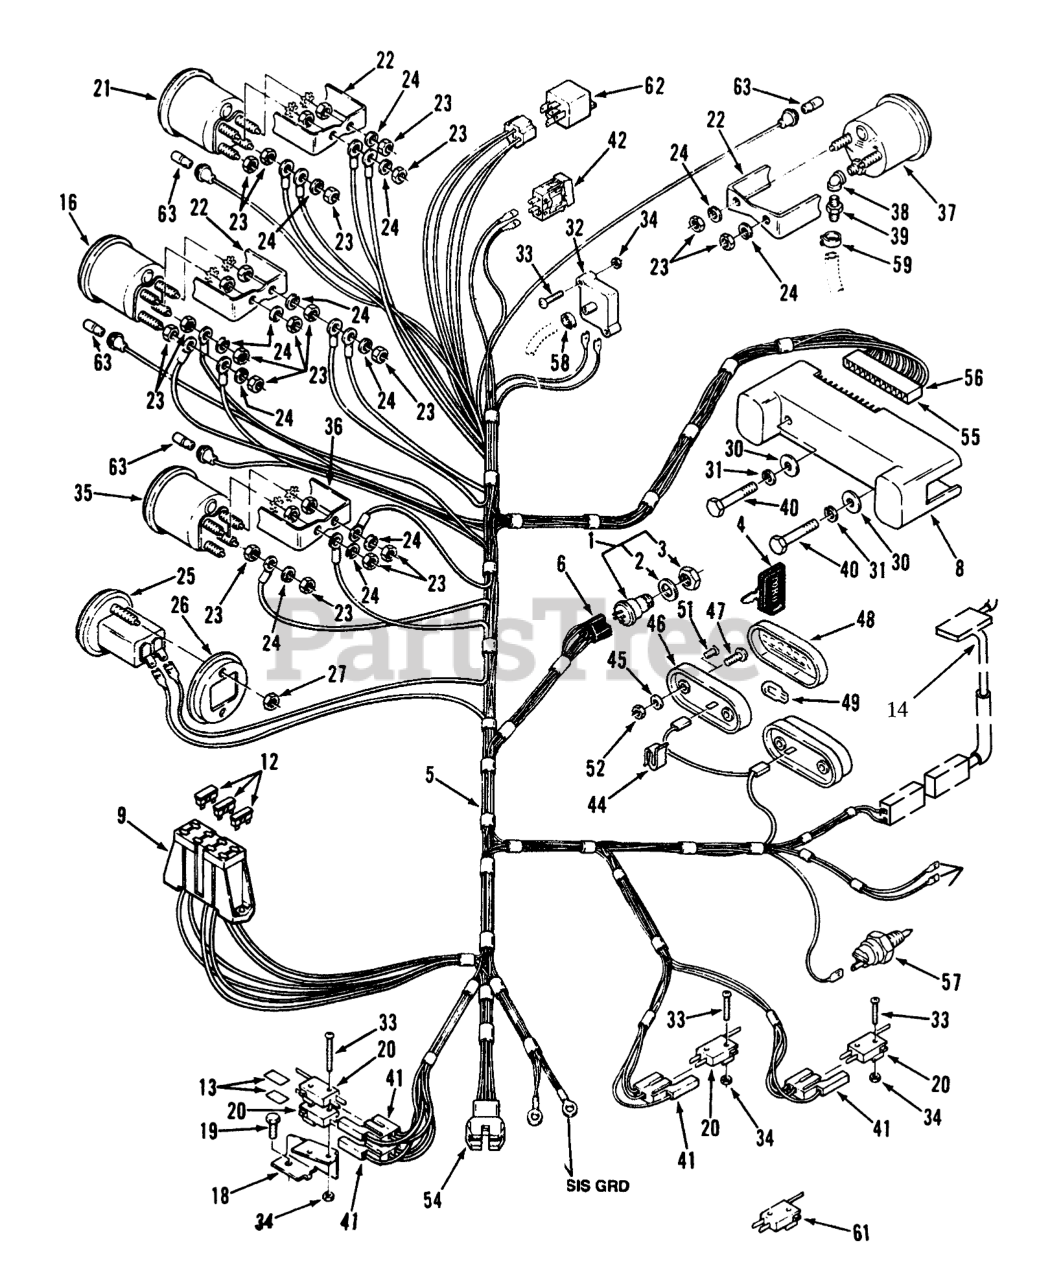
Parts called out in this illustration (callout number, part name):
1	SWITCH-IGNITION
2	Washer
4	KEY-IGNITION
5	WIRING-HARNESS & DIA
6	CONNECTOR-5 WAY-SERV
8	CIRCUIT-BRD 8 LIGHT
9	FUSE-HOLDER 4 WAY
12	FUSE-10 AMP
13	BARRIER - SWITCH
14	SWITCH-SEAT
16	Gauge-Fuel(Includes Item 22)
18	Support-Switch
19	Bolt
20	SWITCH
21	Voltmeter(Includes Item 22)
22	CLAMP-MOUNTING
23	Nut
24	Washer-Lock #10
25	Hourmeter(Includes Item 26)
26	Bracket-Mountin
27	Nut
30	WASHER-FLAT
31	WASHER-LOCK
32	SENSOR-AIR CLEANER
33	Screw
34	NUT HEX 4-40 ELAST
35	Tachometer (Includes Item 36)
36	MOUNTING-BRACKET
37	Gauge-Vacuum (Includes Item 22)
38	ELBOW
39	FITTING STRAIGHT
40	SCREW
41	CONNECTOR BODY
42	Light Switch
44	SPEED CLIP
45	WASHER-LOCK, INT
46	BASE-TAIL LIGHT
47	Screw
48	LENS-TAIL LIGHT
49	LIGHT BULB
51	NUT-HEX
52	NUT-HEX
54	9-CIRCUIT CAP
55	Connector-Male
56	Terminal
57	SENSOR-HYDRO OIL HOT
58	CLAMP-HOSE 5/16"
59	Clamp
61	SWITCH - CLUTCH
62	RELAY
63	LAMP-MINIATURE GE 53X
